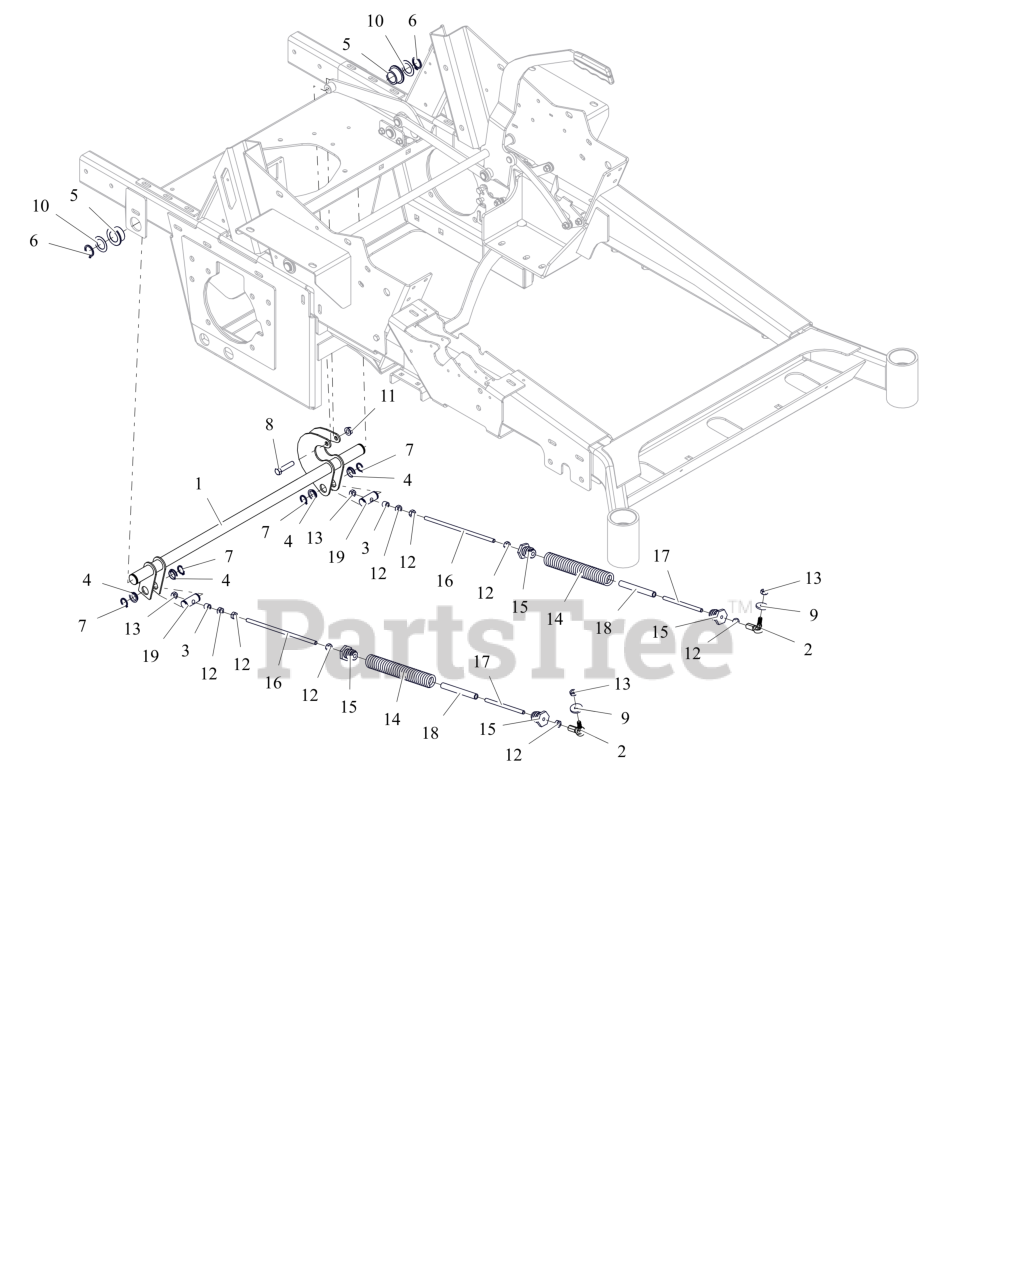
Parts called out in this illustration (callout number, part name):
1	WLDMT, BRAKE REAR PIVOT SHAFT
2	LINKAGE, BALL JOINT .312-24 UNF RH STUD
3	SPACER .50 X .32 X .42
4	BSHG, POLYLINER- .75 SNAP-IN
5	BSHG-FLG1.020X1.385X.75X1.75NY
6	RG-RTNG-EXT 1.00X.078
7	RG-RTNG-EXT .689X.078
8	BLT, HEX .38-16X1.75F G5 ZCC
9	WSHR, FLT .340X1.125X.135 ZCC
10	WSHR-HDND-THRUST 1.00X1.55X.03
11	NUT-LK-CTR-FLG .375-16 GF ZCC
12	NUT, HEX-JAM .3125-24 ZCC
13	NUT-CTRLK .31-24 YWZC
14	SPRG, EXTENSION .063 X .653 X 2.755
15	PLUG, SPRG
16	ROD, TRUNNION END THREADED
17	ROD, BALL END THREADED
18	TUBE, GUIDE
19	TRUNNION, BRAKE PIVOT
